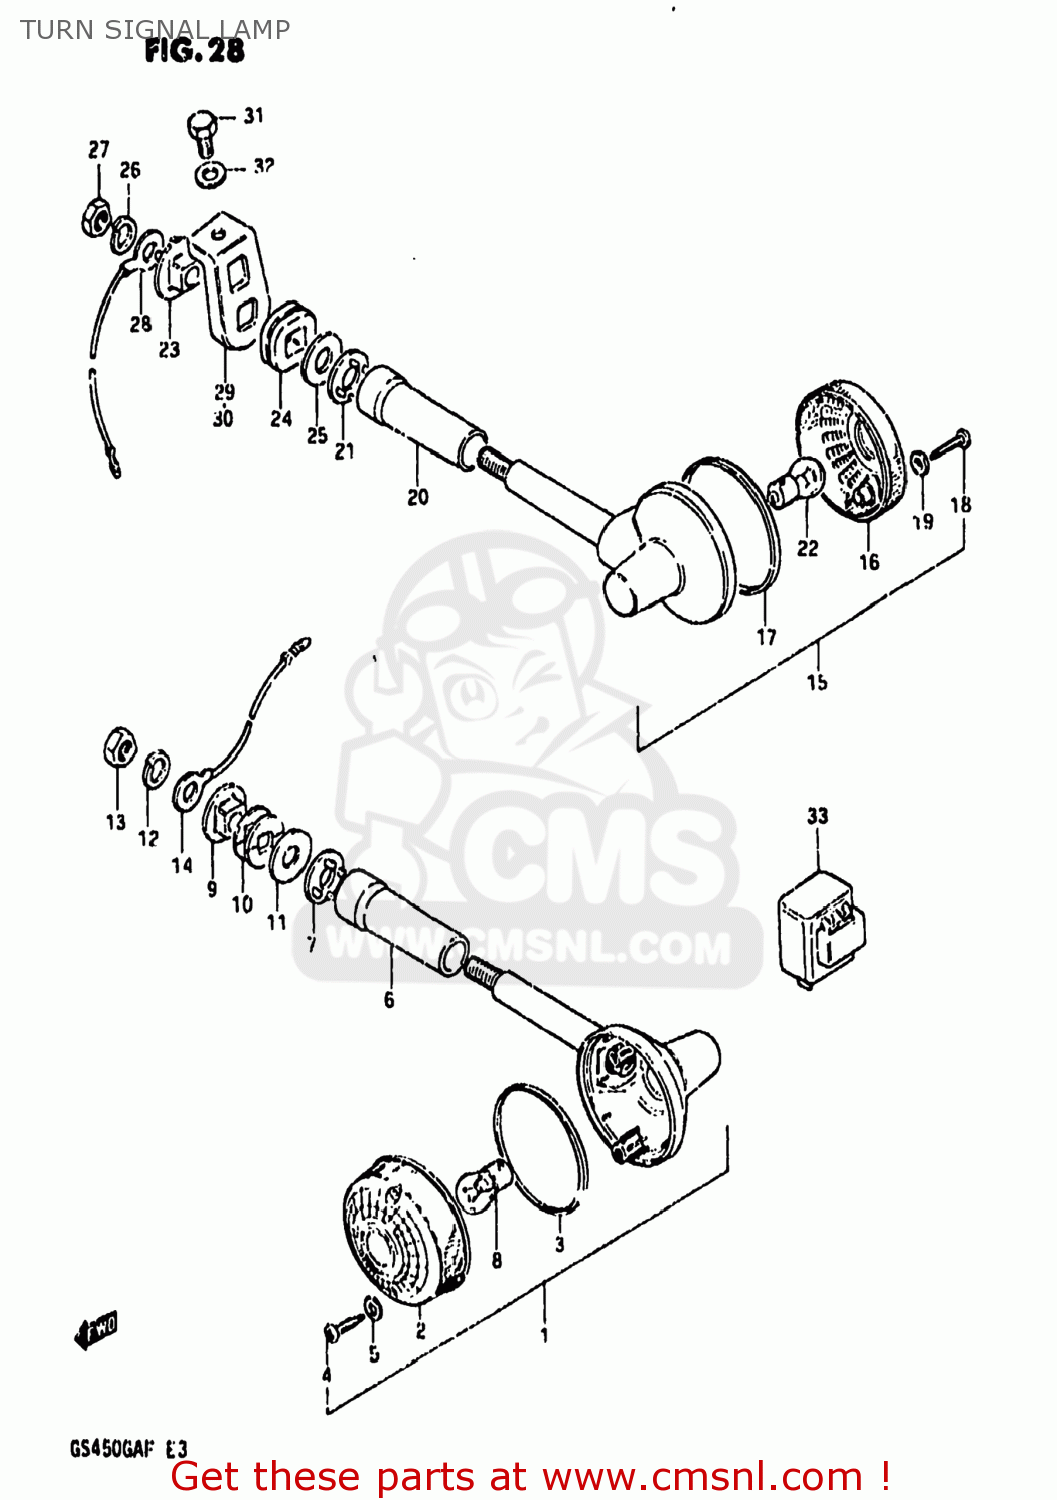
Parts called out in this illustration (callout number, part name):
1	LAMP ASSY,TURNSIGNAL
2	LENS
3	GASKET (NAS)
4	SCREW
5	GASKET (NAS)
6	COVER,STAY
7	SPACER
8	BULB(12V23W,STANLEY,A4577A)
9	SPACER
10	CUSHION
11	WASHER (10.5X30X2.3)
12	LOCK WASHER
13	NUT
14	LEAD WIRE,EARTH
15	LAMP ASSY,TURNSIGNAL
16	LENS
17	GASKET (NAS)
18	SCREW
19	GASKET (NAS)
20	COVER,STAY
21	SPACER
22	BULB(12V23W,STANLEY,A4577A)
23	SPACER
24	CUSHION
25	WASHER (10.5X30X2.3)
26	LOCK WASHER
27	NUT
28	LEAD WIRE,EARTH
29	BRACKET,REAR TURN SIGNAL
30	BRACKET,REAR TURN SIGNAL
31	BOLT 8X12
32	WASHER
33	RELAY ASSEMBLY,TURN SIGNAL
